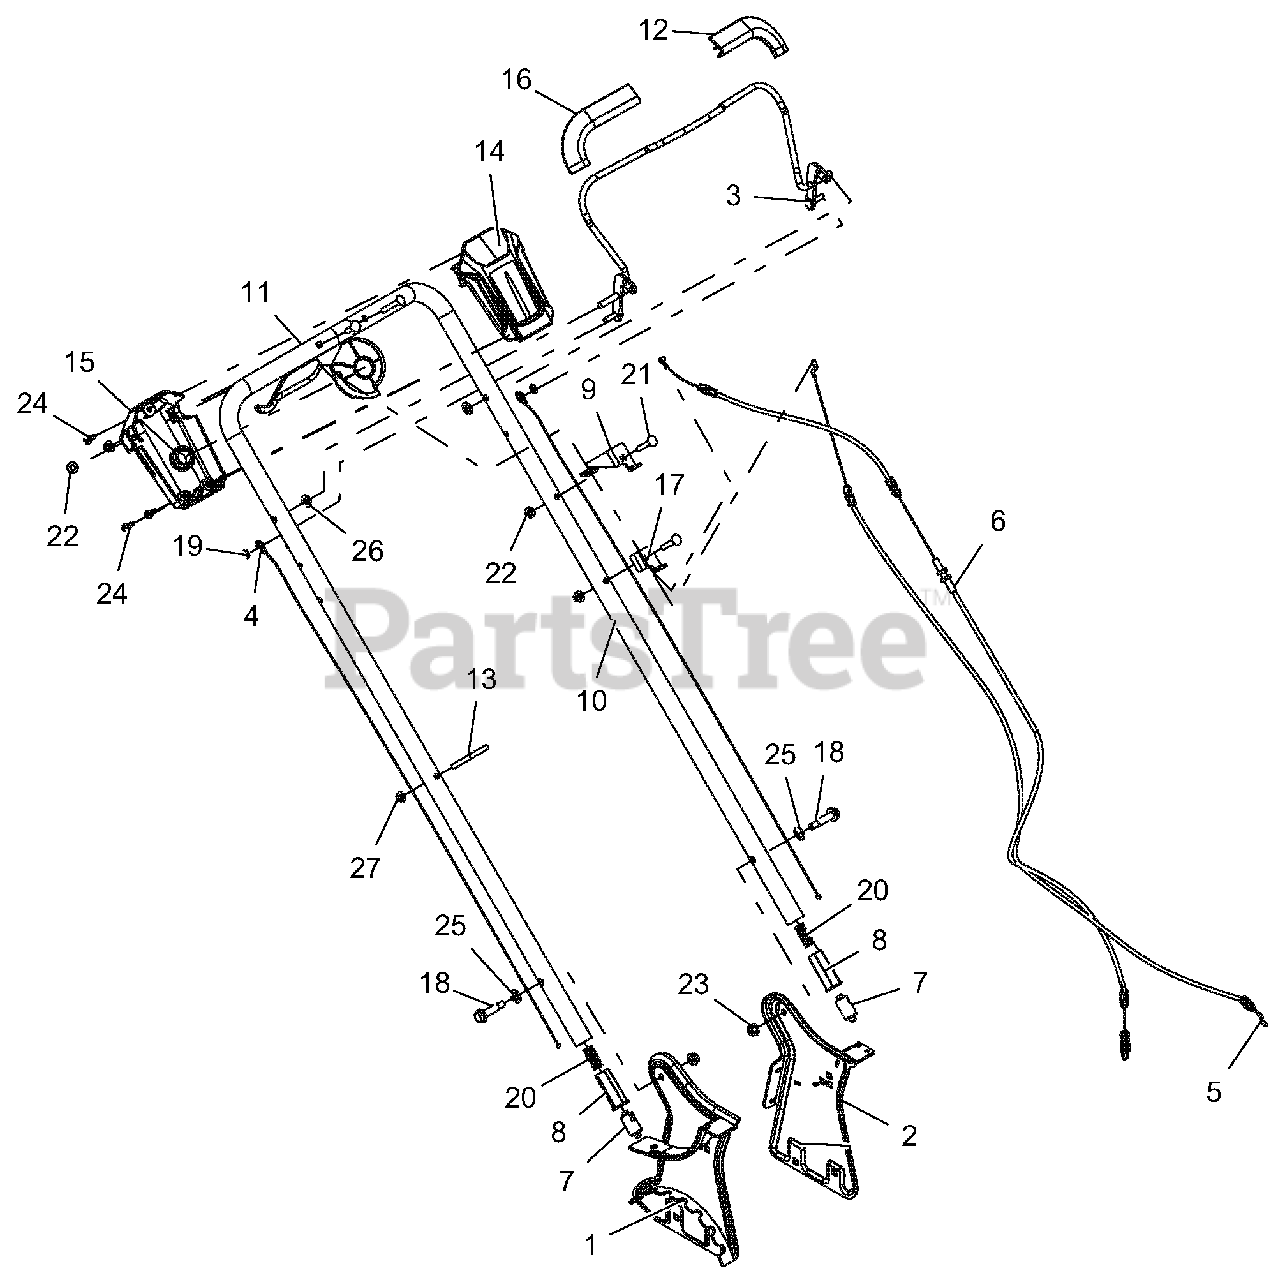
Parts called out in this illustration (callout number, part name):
1	WLDMT, RH SIDE PLATE
2	WLDMT, LH SIDE PLATE
3	BAIL, OPC
4	CABLE, LM HANDLE ADJUST
5	CABLE, OPC
6	CABLE, DRIVE CONTROL
7	PIN, LM HANDLEBAR LOCKING
8	HANDLEBAR ADJUSTMENT INSERT
9	BRKT, CABLE ANCHOR
10	HANDLEBAR,
11	HANDLE, DRIVE CONTROL
12	GUARD, FINGER - LH
13	GUIDE, RECOIL ROPE
14	HOUSING, UPPER DRIVE CONTROL
15	HOUSING, LOWER DRIVE CONTROL
16	GUARD, FINGER - RH
17	BRKT, CABLE - DRIVE
18	BLT, SHLDR .50X1.30X.38-16 GR5
19	RG-RTNG-EXT .250 X .010
20	SPRG, COMPRESSION
21	BLT-RDHDSQNK .25-20X1.50 G5 Y
22	NUT, LK-TOP-FLG .25-20 YWZC
23	NUT, LK-TOP-FLG .312-18 YWZC
24	SCR-TAP #12-14X.75 PLASTITE BLZC
25	WSHR-FL-STL .385x.745x.030 YWZC
26	WSHR-FL-STL.344X.688X.065YWZC
27	NUT-LK-NYL-FLG .25-20 YWZC
